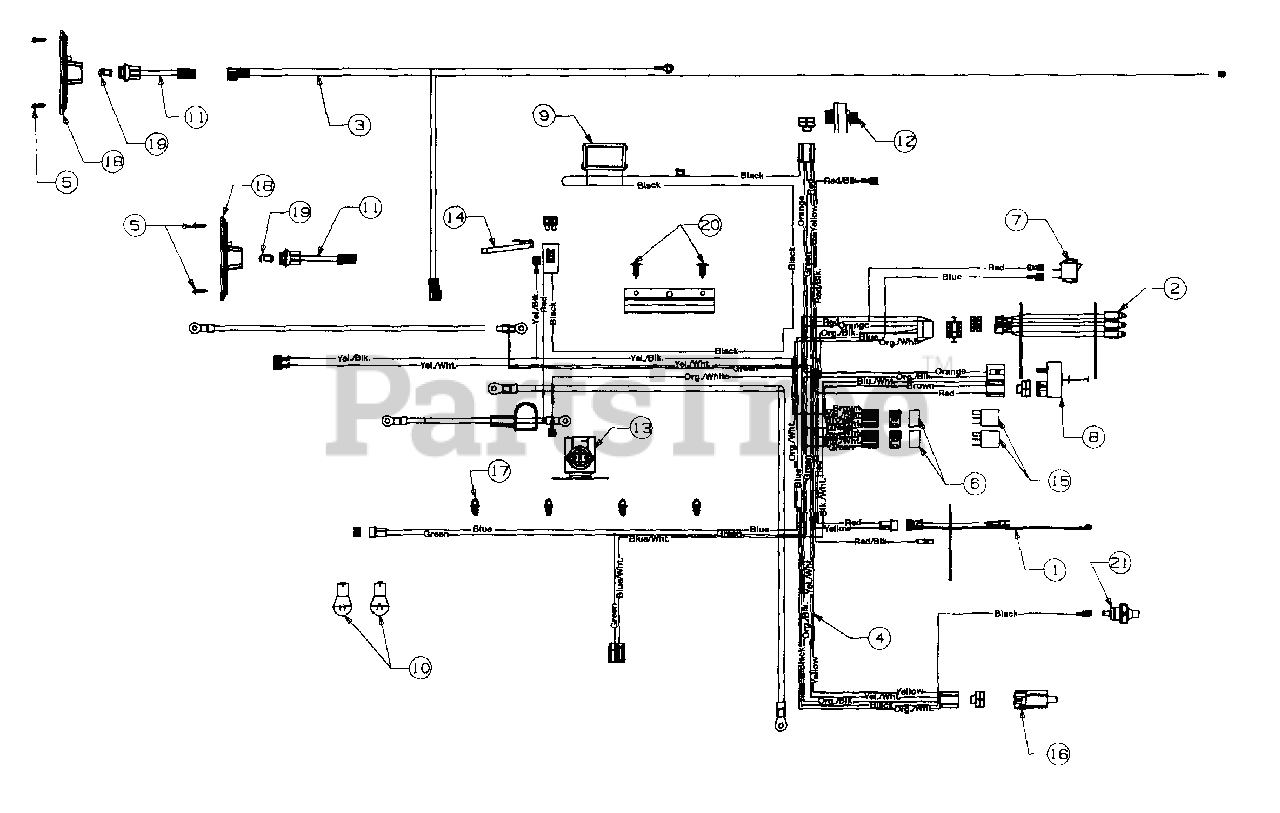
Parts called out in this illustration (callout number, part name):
1	Harness Adapter (Mag.)
2	Harness Adapter (Monitor)
3	Harness Adapter (Tail light)
4	Wire Harness
5	Truss Hd. AB-Tap Scr. #6-32 x .62" Lg.
6	Relay Gasket
7	Light Switch
8	PTO Switch
9	Ammeter
10	Bulb (Headlight)
11	Tail light Harness
12	Ignition Switch
13	Solenoid
14	Safety Switch (Reverse)
15	Relay
16	Safety Switch
17	Wire Retainer Clip
18	Tail light
19	Bulb (Tail light)
20	Ratchet
21	Oil Pressure Switch
